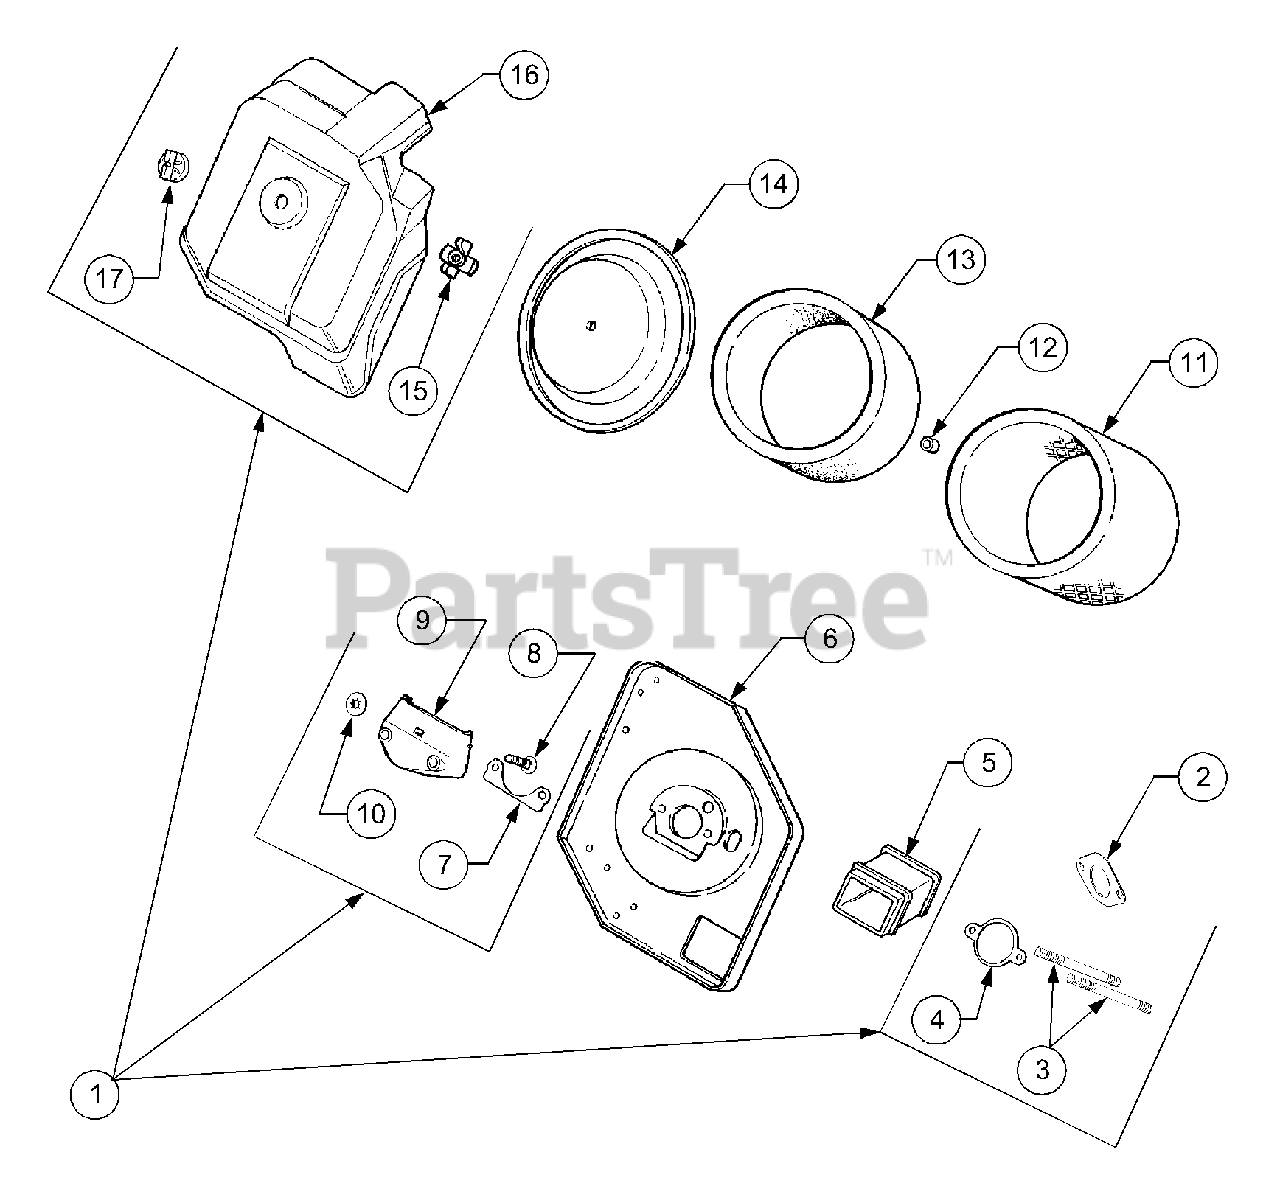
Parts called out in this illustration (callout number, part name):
1	Kit, Fuel Recovery
2	Gasket, Carburetor
3	Stud, M6 x 1.0 x 116
4	Gasket, Air Cleaner
5	Tube, Air Cleaner
6	Base, Air Cleaner
7	Gasket, Collector Plate
8	Bolt, Carriage, M6 x 1.0 x 22
9	Cup, Fuel Spit Back
10	Retainer, Ring
11	Element, Air Cleaner
12	Seal, Inner Air Cleaner
13	Pre-Cleaner, Element
14	Cover, Air Cleaner Element
15	Wingnut, Element Cover
16	Cover, Air Cleaner Base
17	Knob, Air Cleaner Cover
